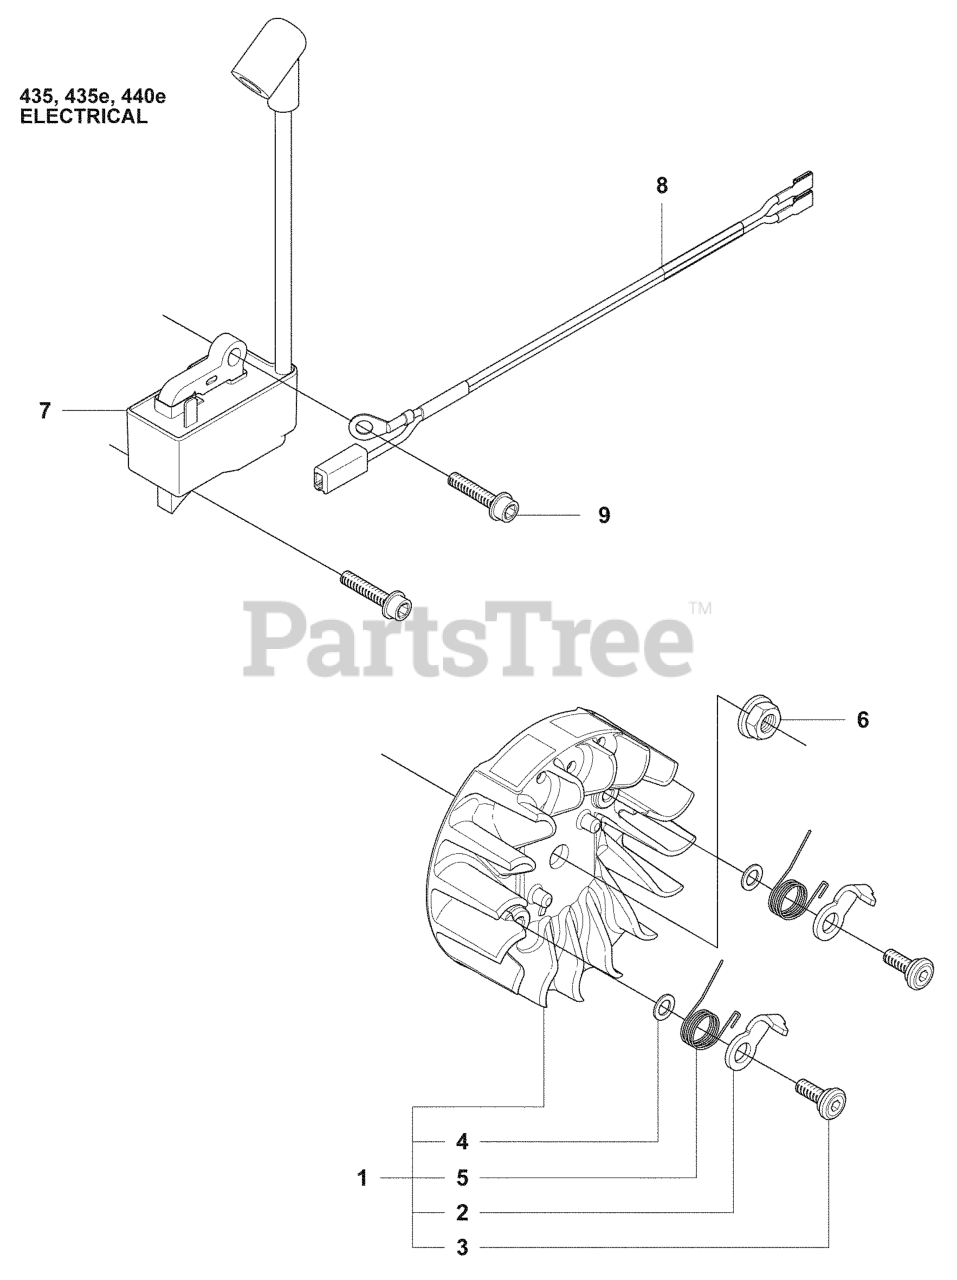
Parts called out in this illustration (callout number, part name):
1	%FLYWHEEL ASSY
2	PAWL
3	SCREW
4	WASHER
5	%SPRING, STARTER CATCH
6	NUT W/ WASHER
7	IGNITION MODULE
8	WIRING ASSY
9	SCREW
